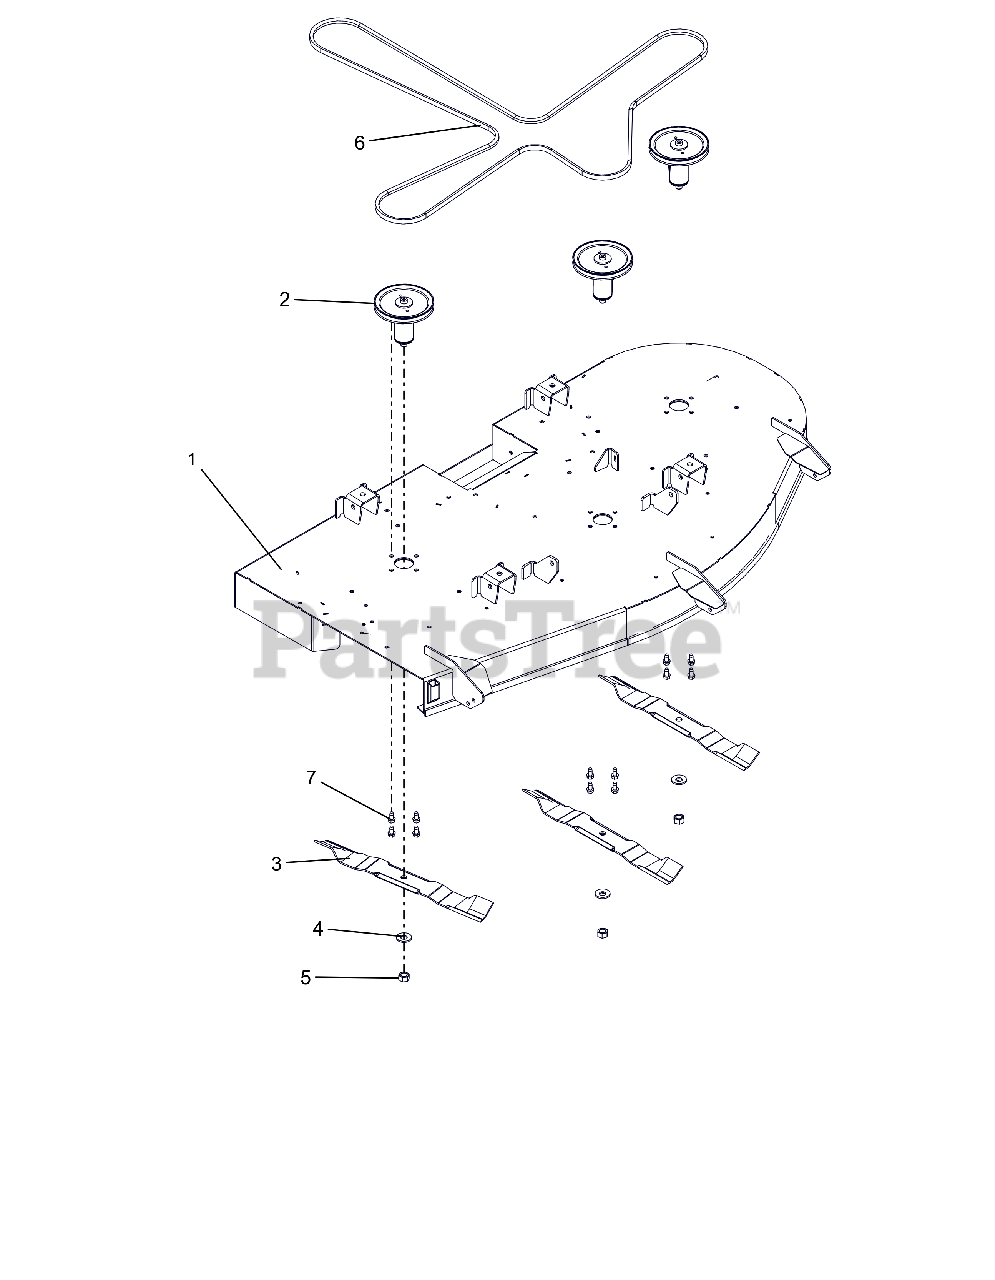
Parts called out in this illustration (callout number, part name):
1	KIT, ARIENS DECK 60" WITH DECALS
2	KIT, DECK SPINDLE ASM-60
3	BLADE, 21" 35 DEG
4	WSHR-BLVL .669X1.535X.138
5	NUT-HEX .62-18 YWZC
6	BELT, HA
7	@SCR-TAP .38-16X.75 HWH TR YWZ
